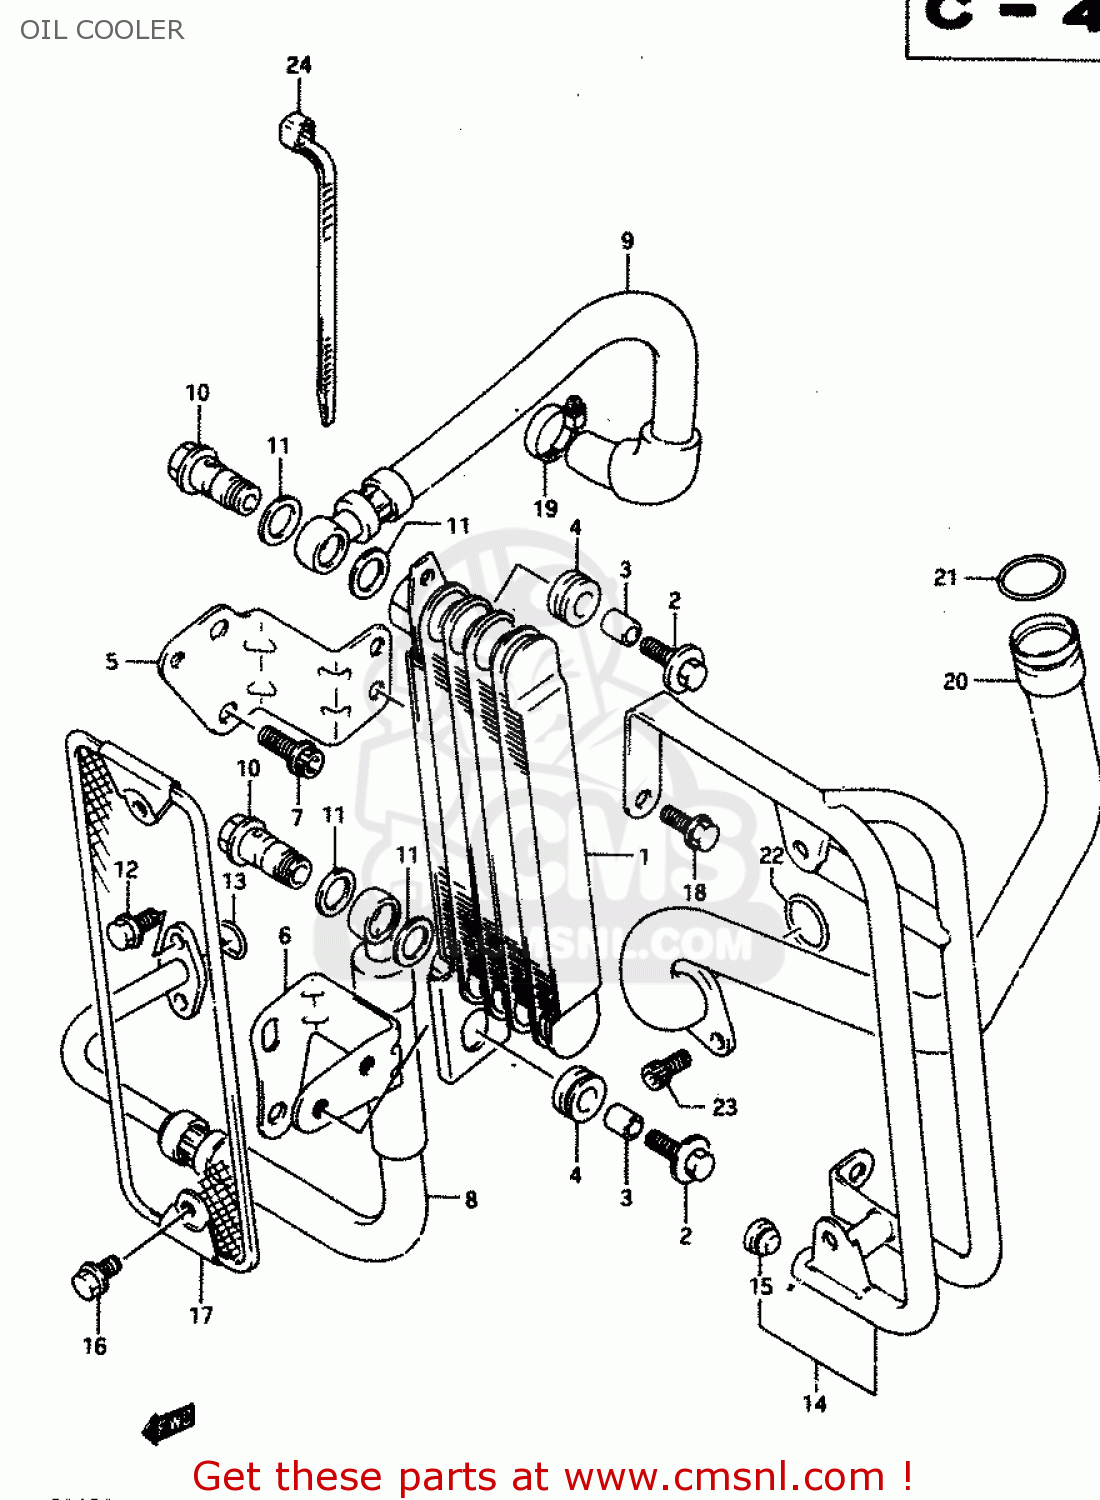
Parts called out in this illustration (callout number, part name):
1	COOLER ASSEMBLY,OIL
2	BOLT 6X20
3	SPACER (6.8X10X10)
4	CUSHION
5	BRACKET,OIL COOLER UPR
6	BRACKET,OIL COOLER,LOWER
7	BOLT
8	HOSE,OIL COOLER NO.1
9	HOSE,OIL COOLER NO.2
10	BOLT UNION
11	GASKET(14X20X1.5) (NAS)
12	BOLT
13	O RING(D:2.4,ID:12.3)
14	GUARD,OIL COOLER
15	PLUG(OD:13)
16	BOLT 6X12
17	BUMPER,OIL COOLER
18	BOLT
19	CLAMP
20	PIPE COMP,OIL RETURN
21	O RING(D:3.7,ID:21.7)
22	O RING(D:2.4,ID:23.7)
23	BOLT
24	CLAMP(L:125)
